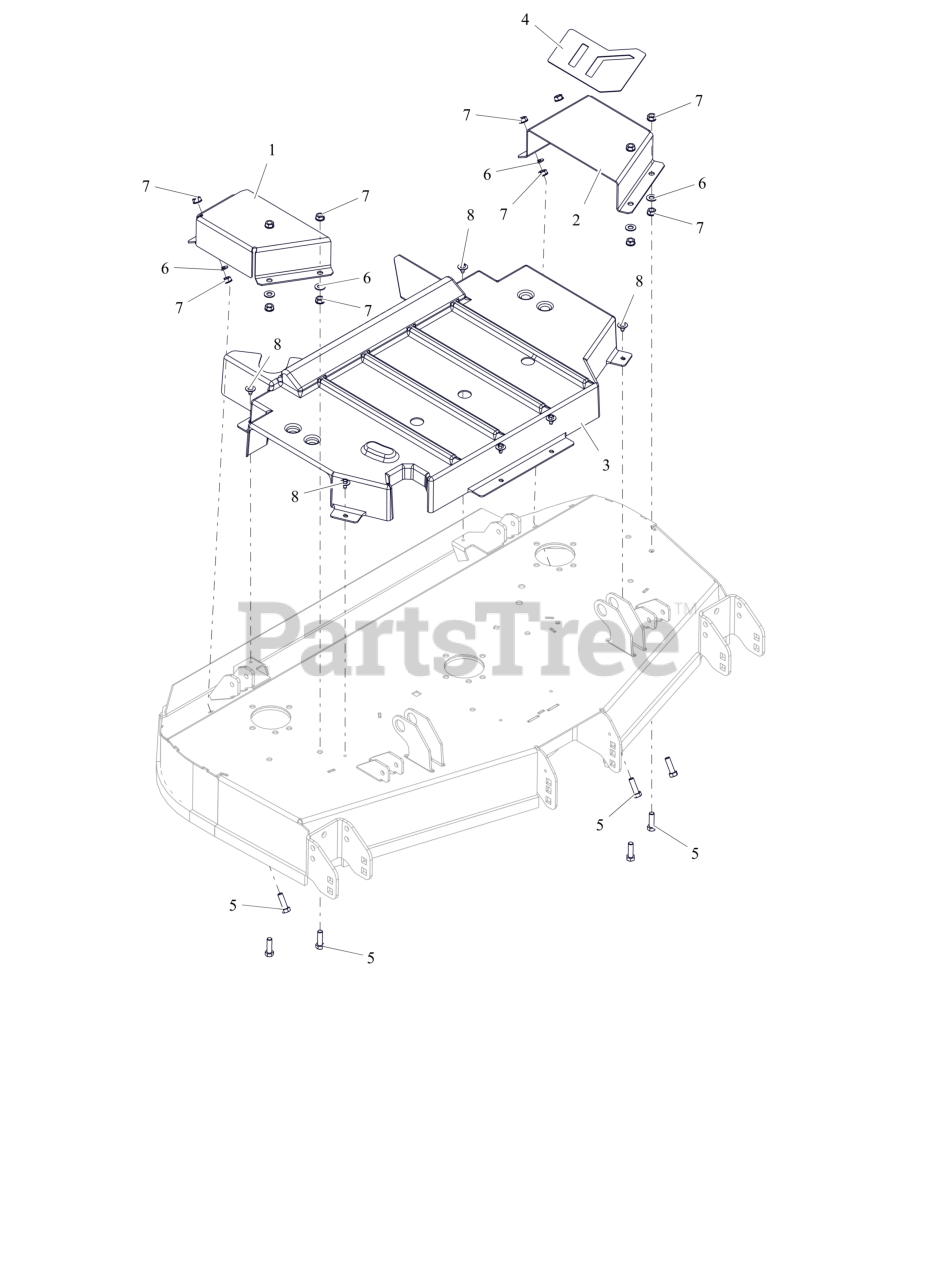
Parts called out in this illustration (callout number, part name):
1	GUARD, BELT 48" RIGHT CE (ORANGE)
2	GUARD, BELT 48" LEFT CE (ORANGE)
3	GUARD, CENTER DECK SPINDLE CE
4	GRIP TAPE 48 BELT COVER
5	BLT, HEX .38-16X1.25 G5 ZCC
6	WSHR,FLT .406X.812X.065 ZCC
7	NUT, SPNLK-FLG .38-16 G5 ZCC
8	SCR, TAP .25-20X.50 LG HWH ZCC
